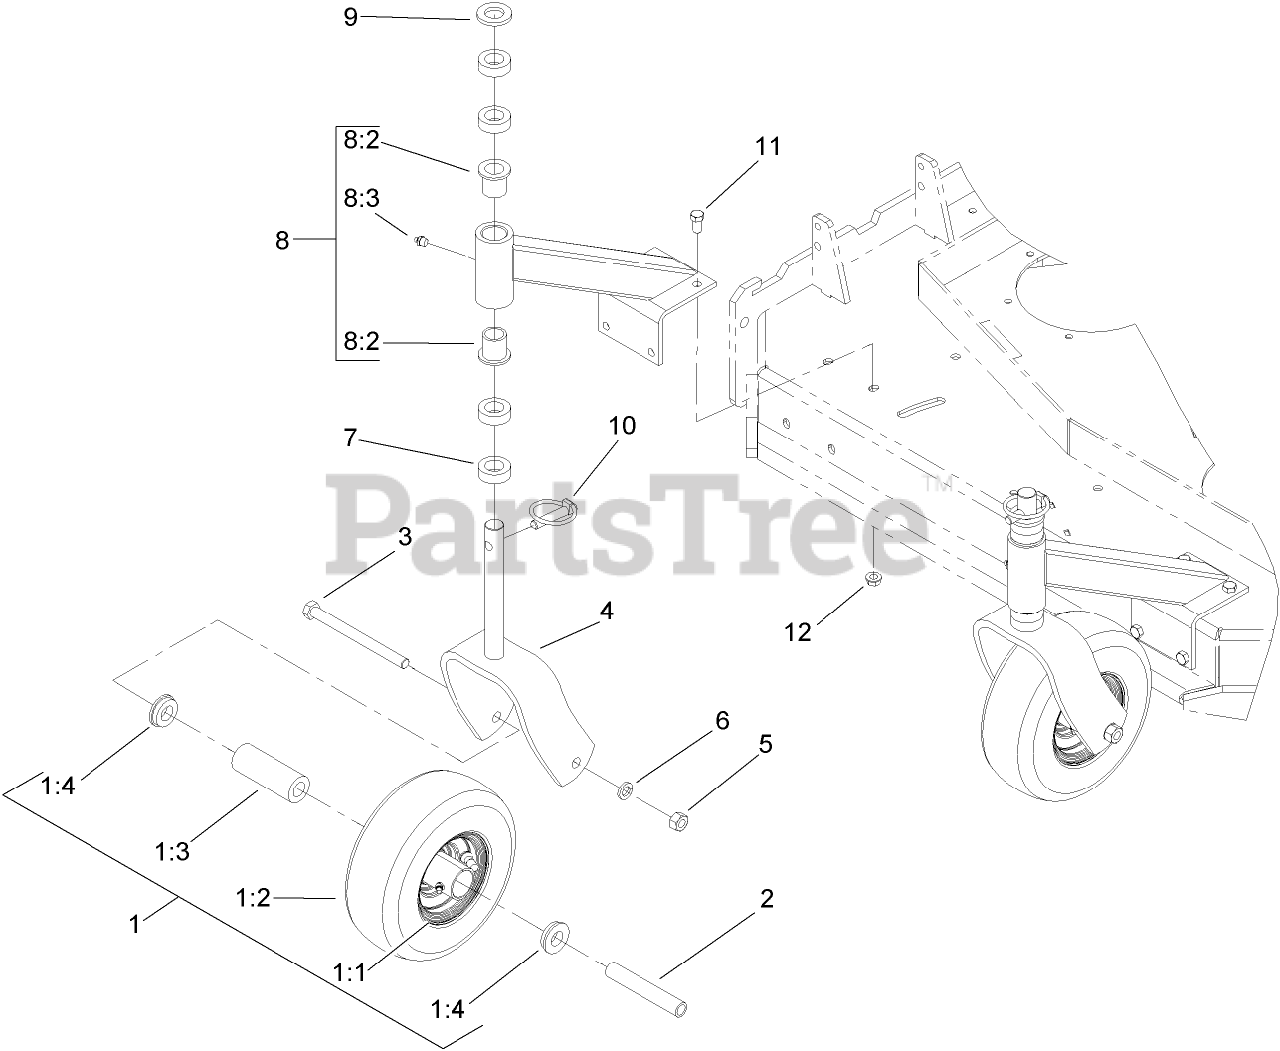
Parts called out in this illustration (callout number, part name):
1	WHEEL AND TIRE ASM
1:1	Rim
1:3	BEARING
1:4	BUSHING
2	SPACER
3	SCREW-HH
4	FORK
5	NUT-HH
6	WASHER-LOCK
7	SPACER-CASTER
8	SUPPORT ASM
8:2	BEARING-FLANGED
8:3	FITTING-GREASE
9	WASHER-FLAT
11	SCREW-HH
12	NUT-HHF, WHIZ
